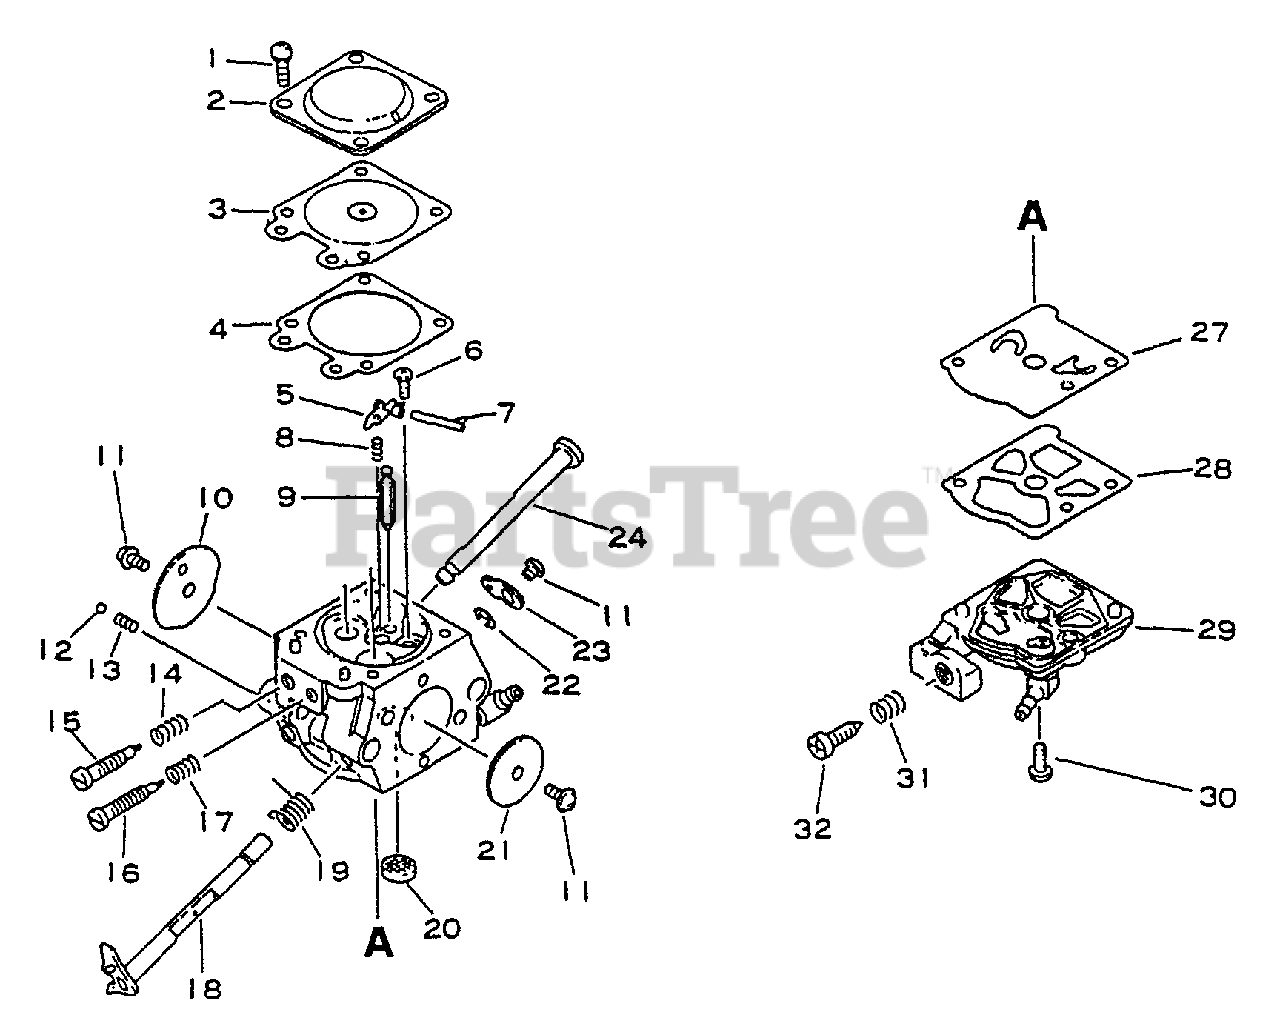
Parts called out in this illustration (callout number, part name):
1	SCREW
2	COVER, METERING DIAPHRAGM
3	DIAPHRAGM, METERING
4	GASKET, METERING
5	LEVER, METERING
6	SCREW, METERING LEVER PIN
7	PIN, METERING LEVER
8	SPRING, METERING LEVER
9	VALVE, INLET NEEDLE
10	VALVE, THROTTLE
12	BALL, CHOKE FRICTION
14	SPRING
15	NEEDLE, HIGH SPEED
16	NEEDLE, LOW SPEED
17	SPRING, NEEDLE
18	SHAFT, THROTTLE
19	SPRING, RETURN
20	STRAINER
21	VALVE, CHOKE
22	CLIP, THROTTLE SHAFT
23	LEVER, THROTTLE
24	SHAFT, CHOKE
27	DIAPHRAGM, PUMP
28	GASKET, PUMP
29	COVER, FUEL PUMP
31	SPRING, IDLE ADJUST
32	SCREW, IDLE ADJUST
